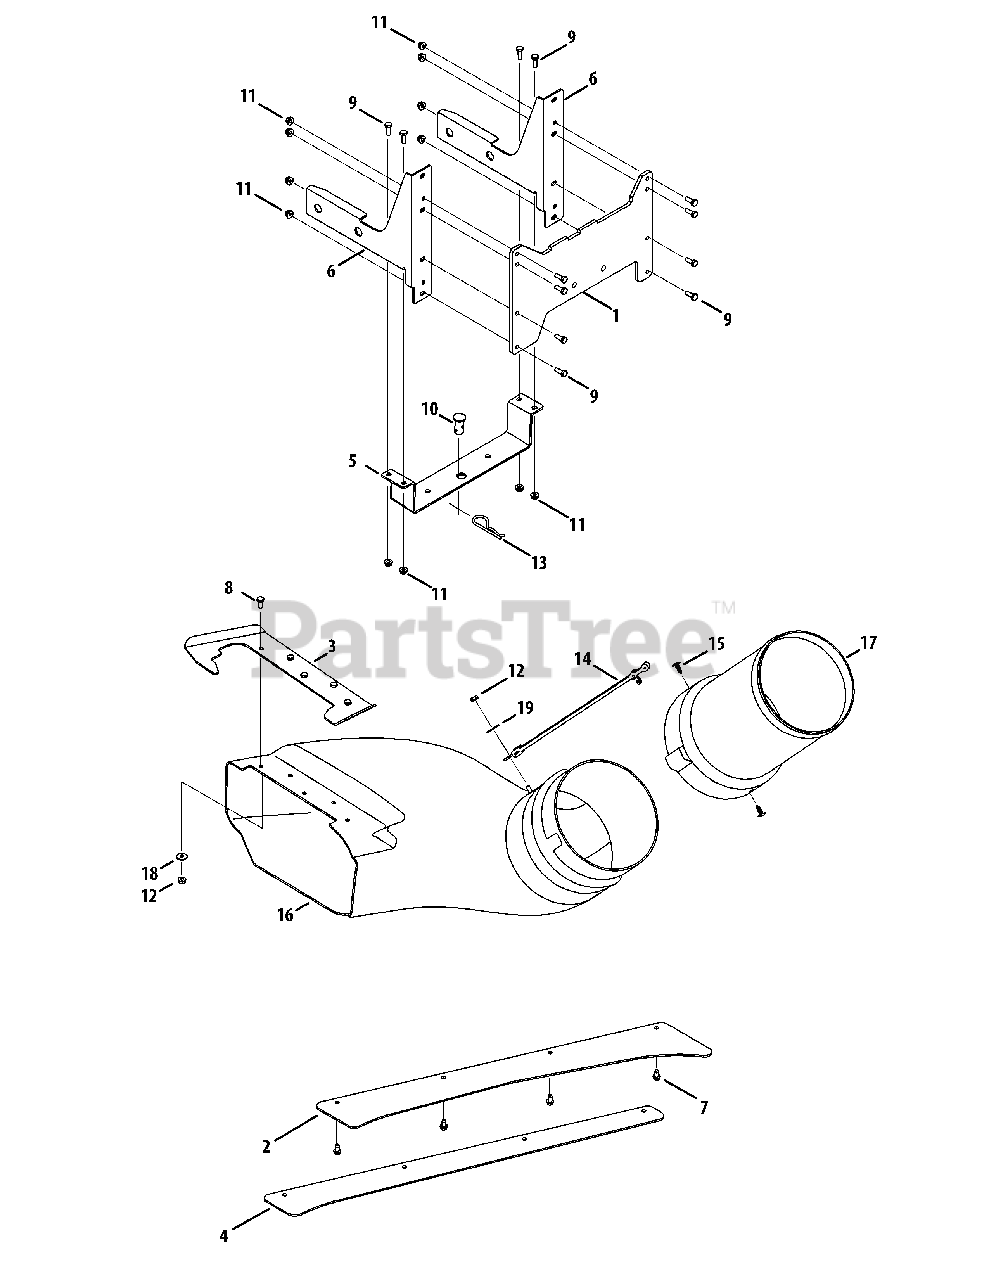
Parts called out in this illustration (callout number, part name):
6	Catcher Support Bracket
7	Tap Screw, 1/4-20 x 0.500
8	Hex Head Screw, 1/4-20 x.620
9	Hex Head Screw, 1/4-20 x .75
10	Clevis Pin, .62 DIA.
11	Flange Lock Nut, 1/4-20 Nylon
12	Flange Lock Nut, 1/4-20
13	Internal Cotter Pin, .148 x 3.00
14	Chute Strap
15	Ratchet Clip, .250 DIA
16	Chute Elbow
17	Bagger Chute Adaptor, 8 x 13.5
18	Belleville Washer, .265 x .75 x .062
19	Flat Washer, .265 x 1.000 x .030
